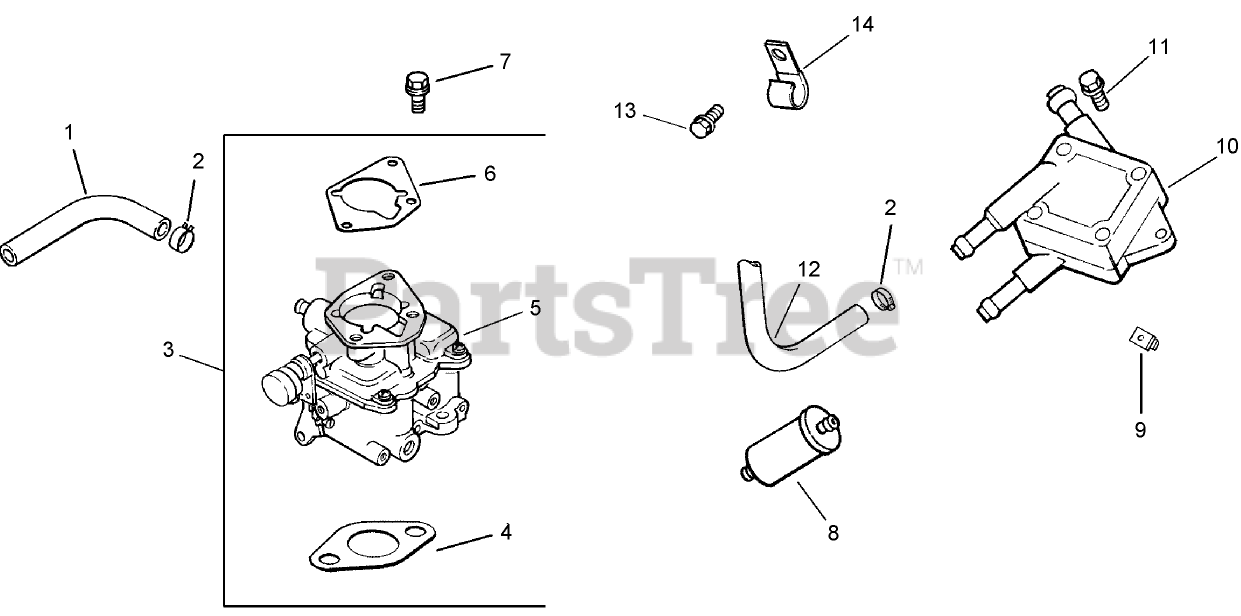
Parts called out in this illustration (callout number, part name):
1	Line-Fuel (9.5)
2	CLAMP-HOSE, SPRING (1/2)
3	Kit, carburetor w/gasket (Includes 4-6)
4	Gasket-Carburetor
5	Carburetor ASM
6	GASKET-BASE, AIR CLEANER
7	SCREW-FLANGE (M6X1.0X30)
8	Filter-Fuel
9	Nut-Plastic
10	PUMP-FUEL
11	SCREW-TAP (M6X1.7X18)
12	Line-Fuel, Flexible (15.5)
13	Screw-HF (M6x1.0x12)
14	CLIP-CABLE
